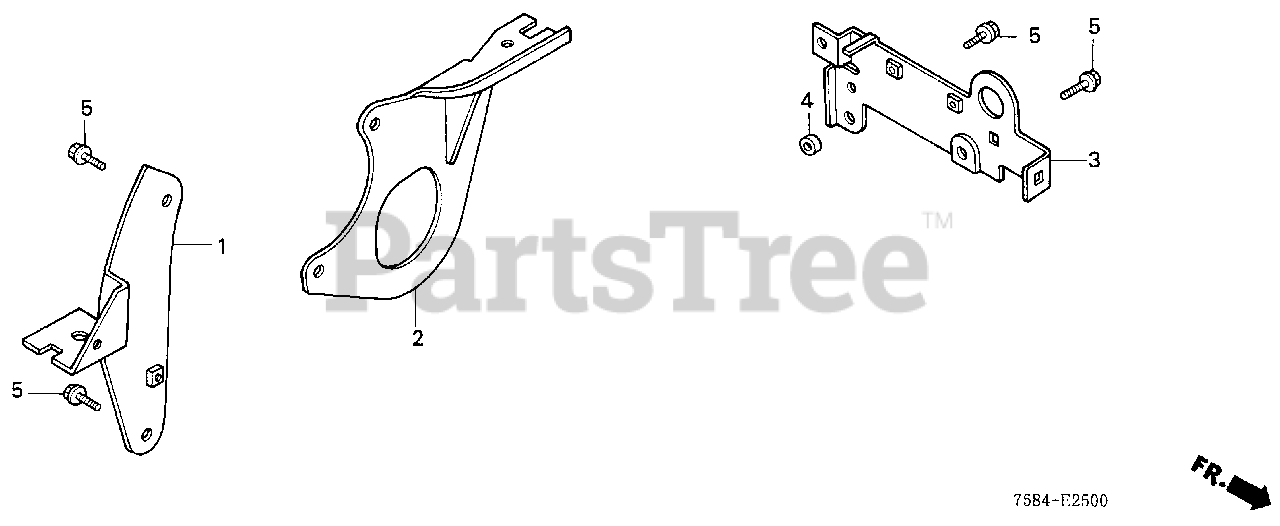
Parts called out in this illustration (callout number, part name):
1	BRACKET, R. RR. ENGINE MOUNTING
2	BRACKET, L. RR. ENGINE MOUNTING
3	HOOK, ENGINE
4	WASHER, PLAIN
5	BOLT, FLANGE (8X20)
